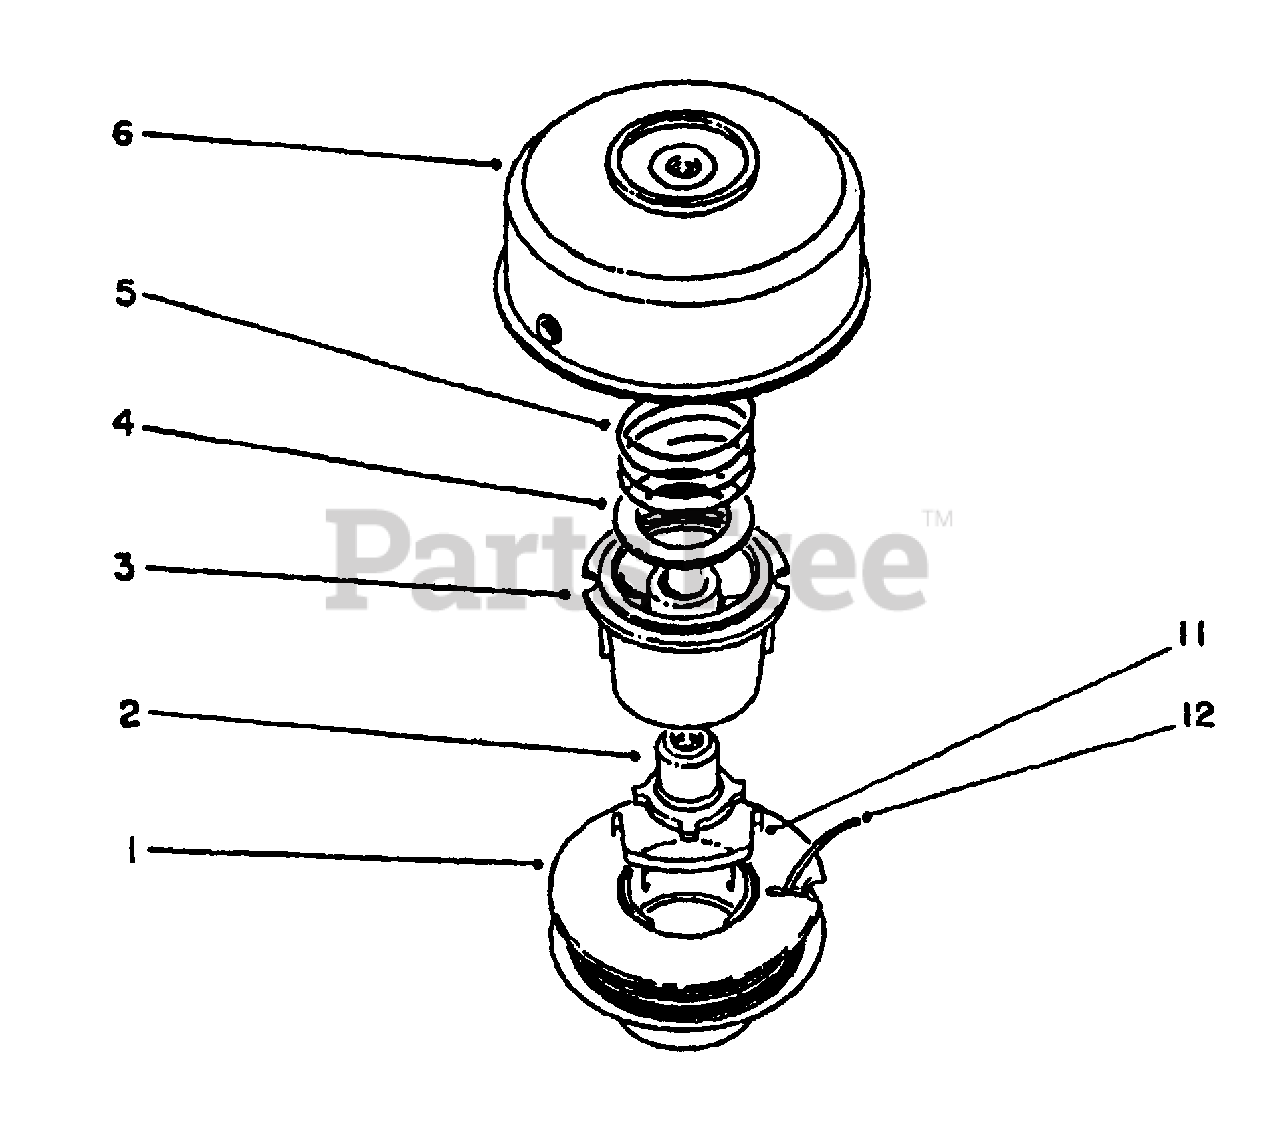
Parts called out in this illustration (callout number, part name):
1	Spool Prewound .095 Dia. (30' Incl. Ref. #11)
2	Driver L.H.
3	Core-Spool
6	Drum w/Eyelet
